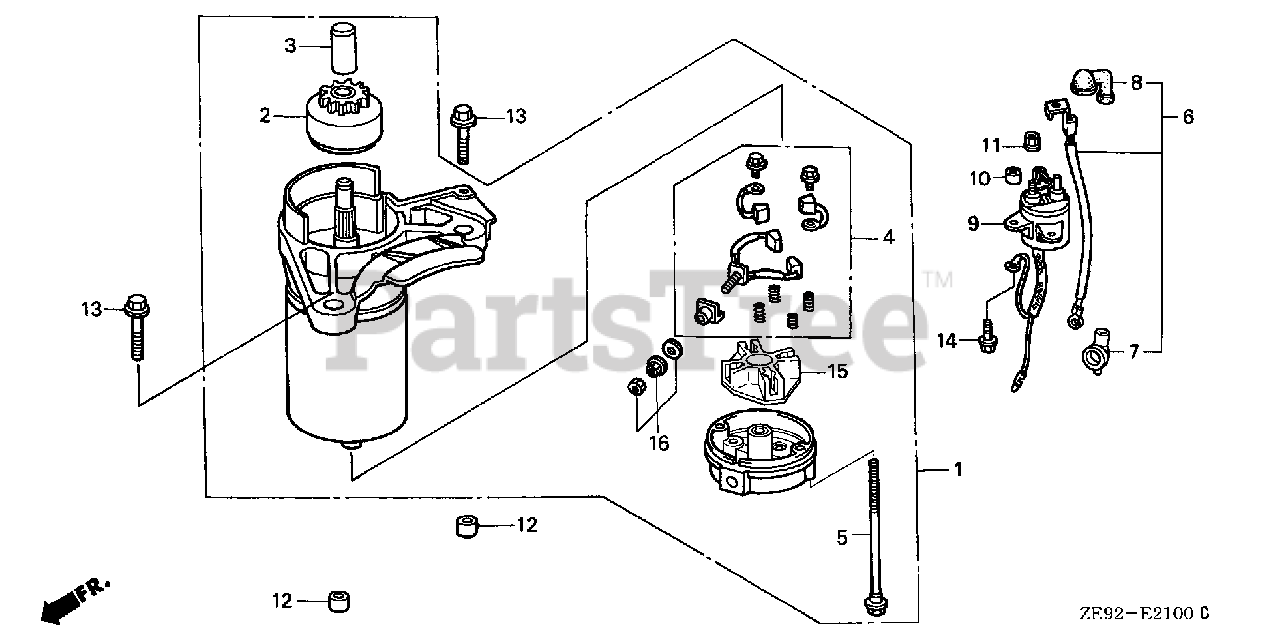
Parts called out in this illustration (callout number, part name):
1	STARTER MOTOR ASSY.
2	DRIVE ASSY.
3	STOPPER SET, PINION
4	BRUSH SET
5	BOLT, THROUGH
6	WIRE, MAGNETIC SWITCH
7	COVER, STARTER TERMINAL
8	COVER, MAGNETIC SWITCH TERMINAL
9	SWITCH ASSY., STARTER MAGNETIC
10	COLLAR, DISTANCE
11	NUT-WASHER (6MM)
12	PIN, DOWEL (10X12)
13	BOLT, FLANGE (8X35)
14	BOLT, FLANGE (6X25)
